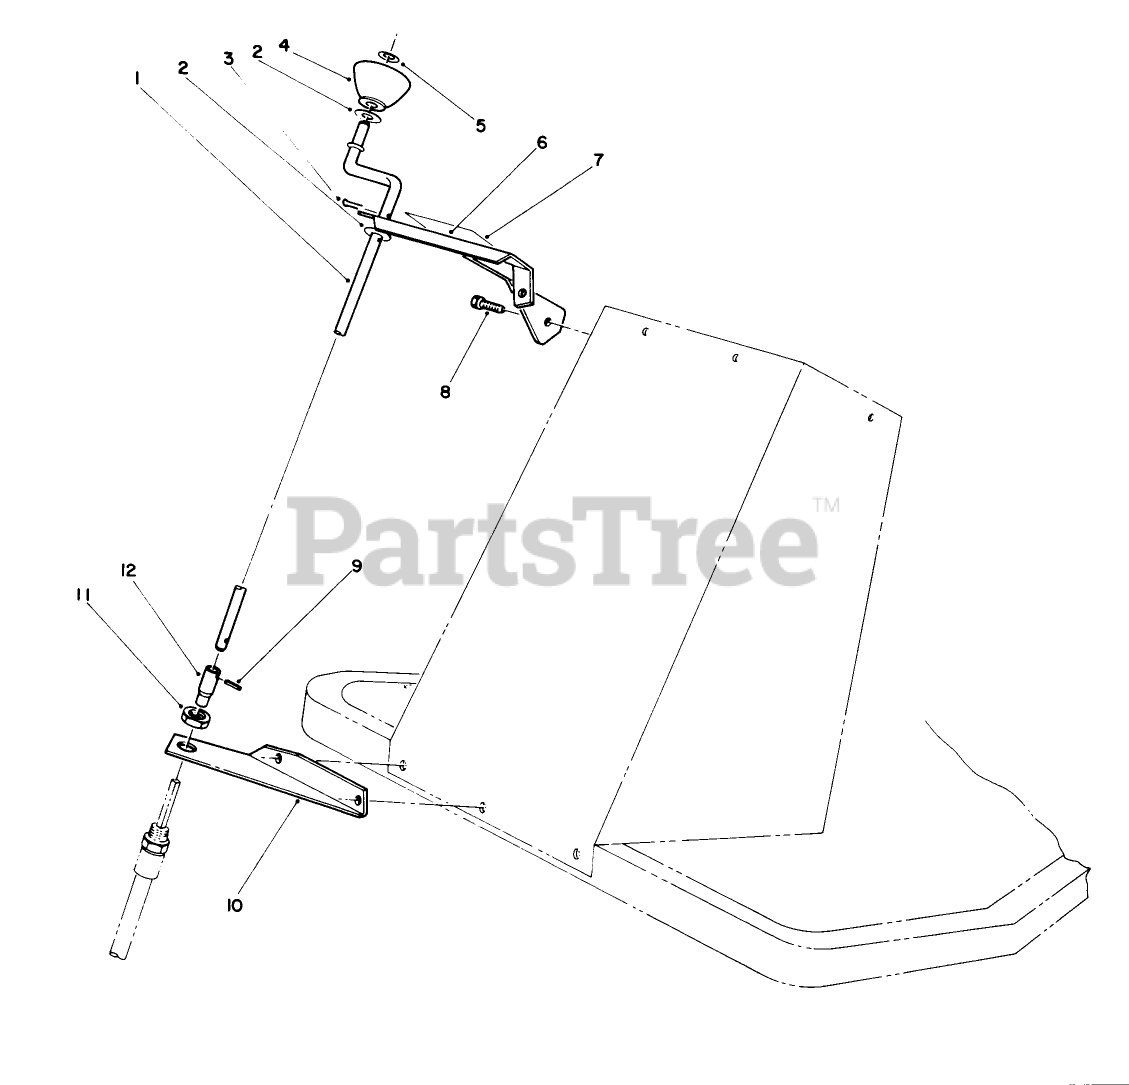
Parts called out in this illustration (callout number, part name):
1	CHUTE CONTROL ROD
2	WASHER-FLAT
3	PIN-COTTER
4	KNOB-CHUTE
5	NUT-PUSH
6	TOP BRKT R
7	Decal-Chute Rotation
8	SCREW-HH
9	PIN-SPRING
10	BOTTOM BRKT R
11	LOCKNUT
12	COUPLER
